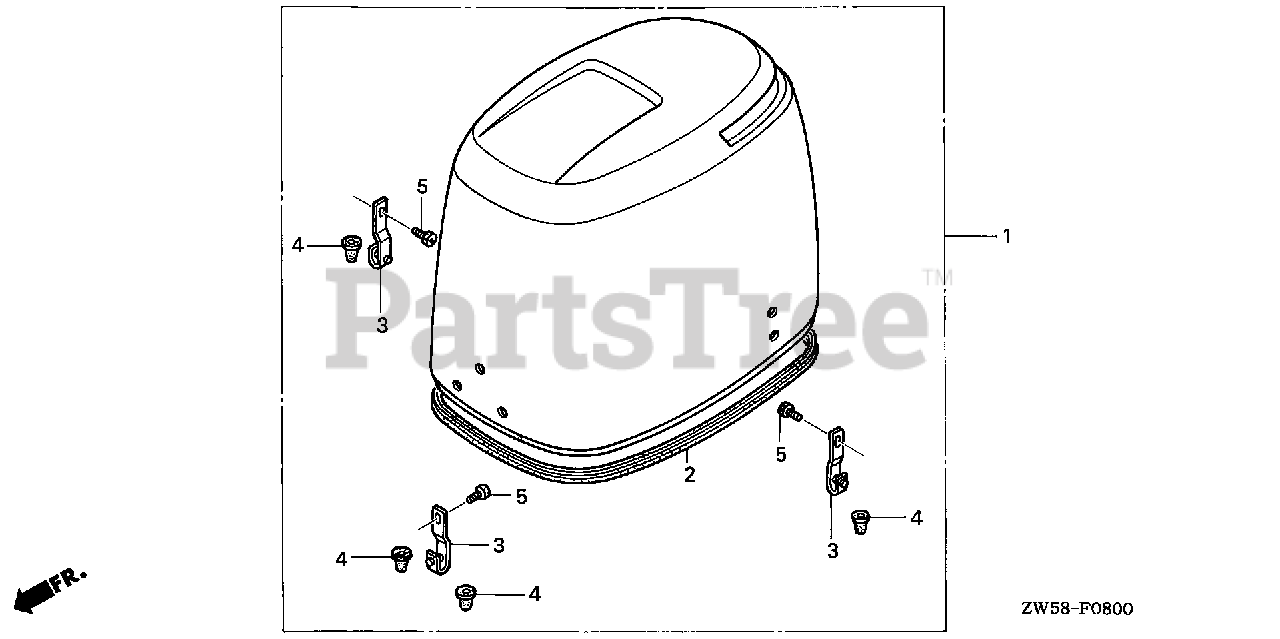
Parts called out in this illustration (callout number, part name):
1	COVER ASSY., ENGINE *NH282MU* (OYSTER SILVER METALLIC-U)
2	SEAL, ENGINE COVER
3	HOOK, ENGINE COVER
4	DAMPER, HOOK
5	BOLT, SOCKET (8X16)
